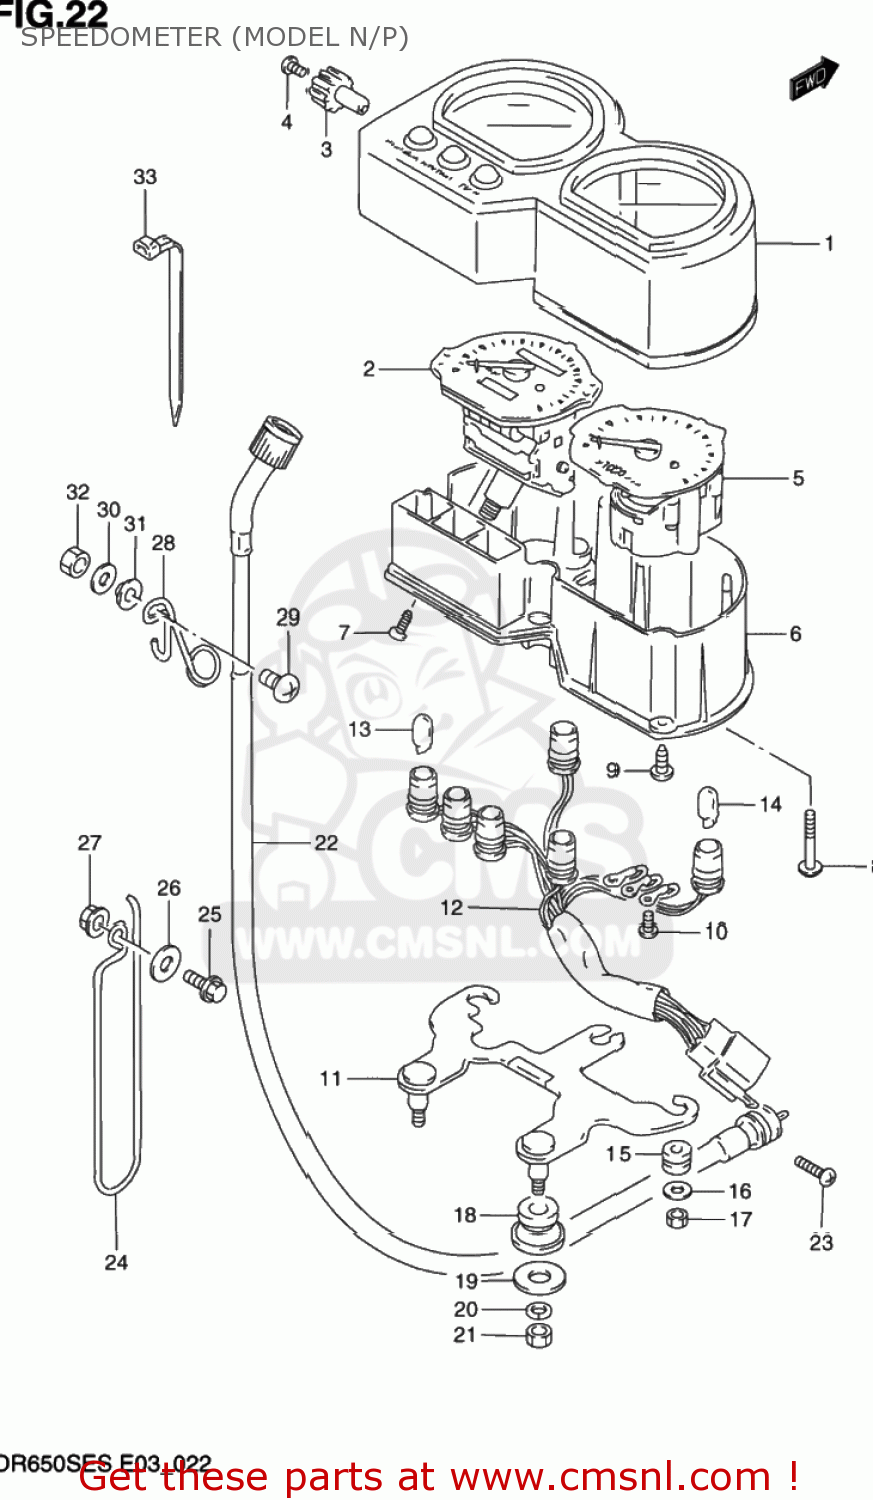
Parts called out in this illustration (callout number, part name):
1	VISOR
2	SPEEDOMETER (MILE/KILO)
3	KNOB
4	ROTOR,SPEED
5	TACHOMETER
6	CASE,METER
7	SCREW
8	SCREW
9	SCREW
10	SCREW
11	BRACKET
12	SOCKET,METER
13	BULB(12V3.4W,T10)
14	BULB(12V1.7W,T10,WB121)
15	CUSHION
16	WASHER (5.5X16X1.2)
17	NUT 5MM
18	CUSHION,METER BRACKET
19	WASHER (8.5X20X1.6)
20	WASHER,LOCK,8.
21	NUT ,8MM
22	CABLE ASSY,SPEEDOMETER
23	SCREW
24	GUIDE,METER CABLE NO.2
25	BOLT 6X20
26	WASHER
27	NUT
28	GUIDE,METER CABLE NO.3
29	SCREW
30	WASHER
31	WASHER
32	NUT
33	CLAMP(L:125)
